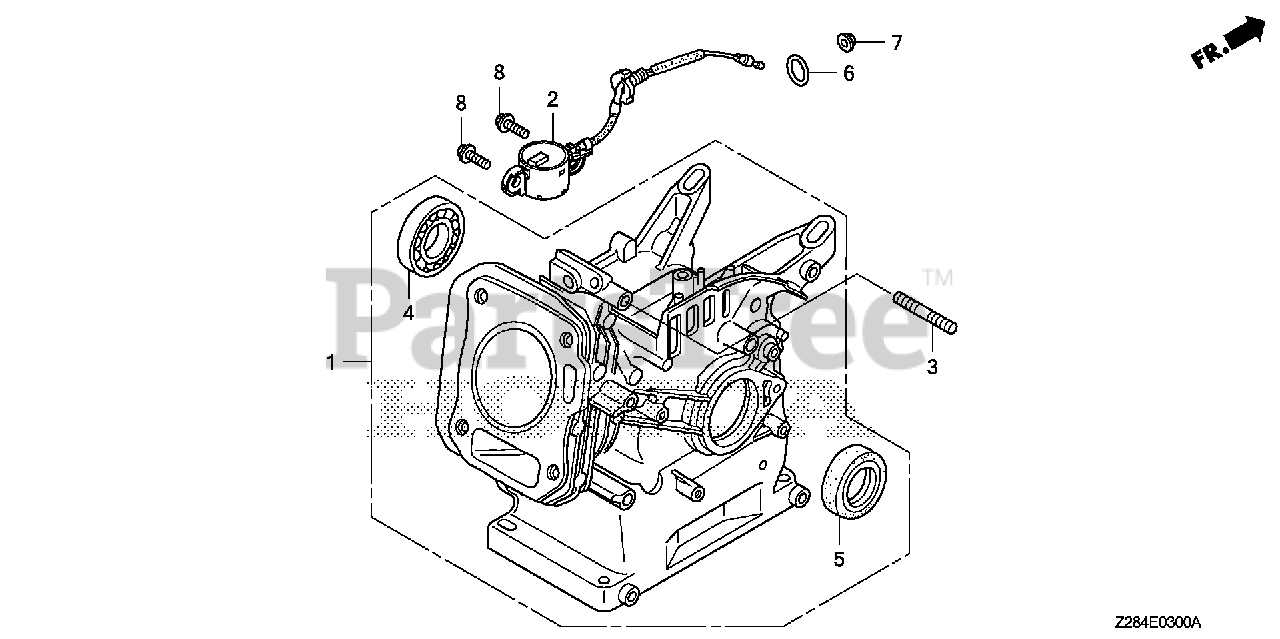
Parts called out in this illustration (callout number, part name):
1	CYLINDER ASSY.
2	SWITCH ASSY., OIL LEVEL
3	BOLT, STUD (6X25)
4	BEARING, RADIAL BALL (6205TMB) (NTN)
4	BEARING, RADIAL BALL (6205) (NSK)
5	OIL SEAL (25X41X6) (NOK)
6	O-RING (13.5X1.5) (ARAI)
6	O-RING (14MM) (NOK)
7	NUT, FLANGE (10MM)
8	BOLT, FLANGE (6X12)
